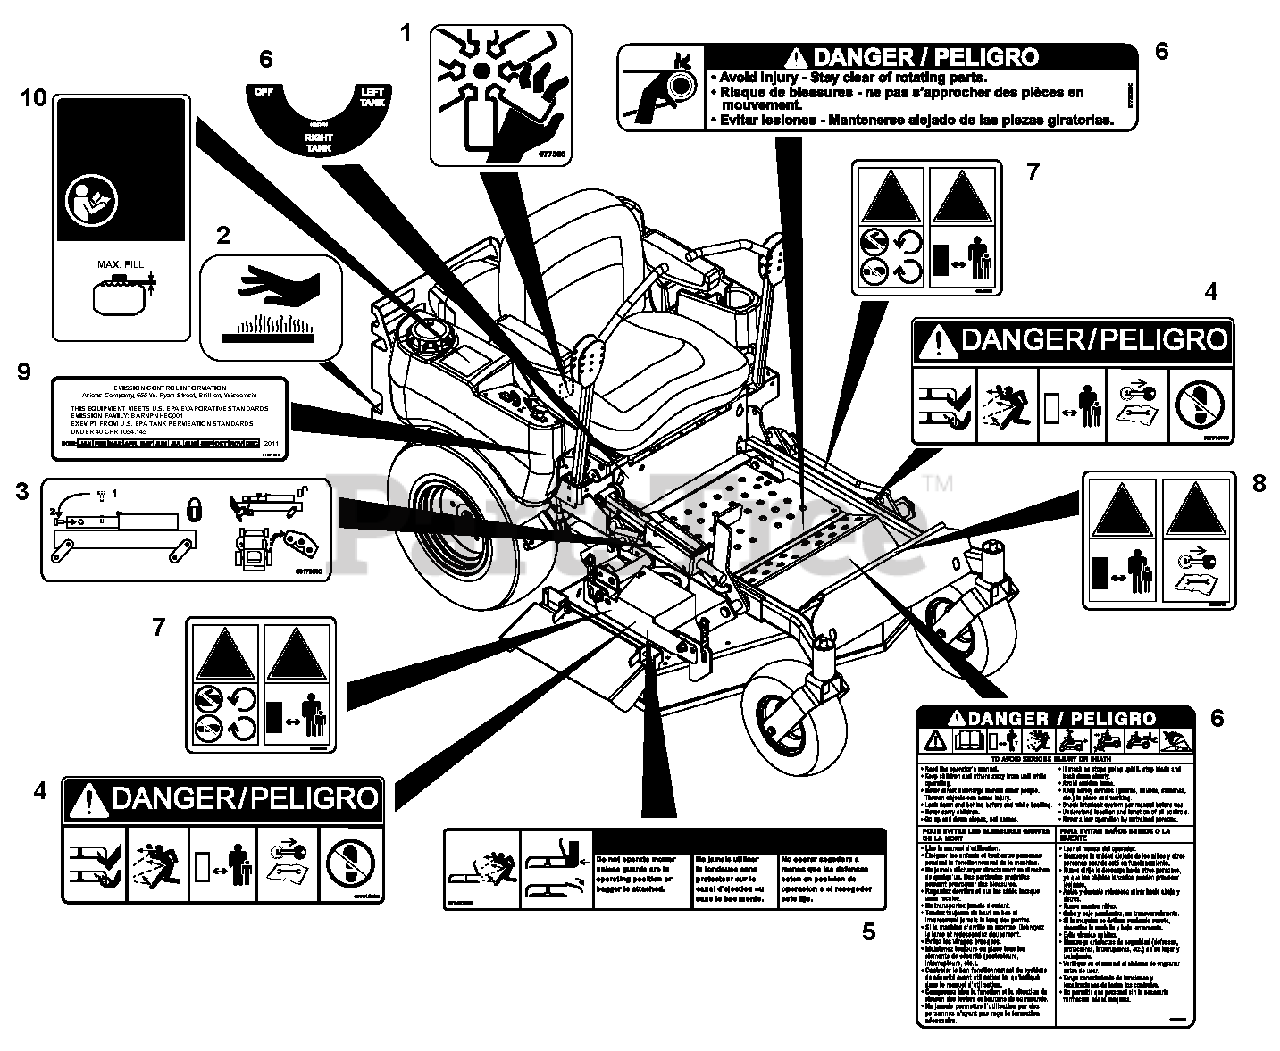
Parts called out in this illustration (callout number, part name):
1	Decal, Danger Fan
2	Decal, Hot Surface
3	Decal, Deck Service
4	Decal, Mower Pan Head Danger
5	Decal, Warning
6	Set, Decal Common Danger/Fuel
7	Decal, CE Deck
8	Decal, CE Caution
9	Label, EPA Non-Compliant Tank
10	Decal, Fuel Warning
